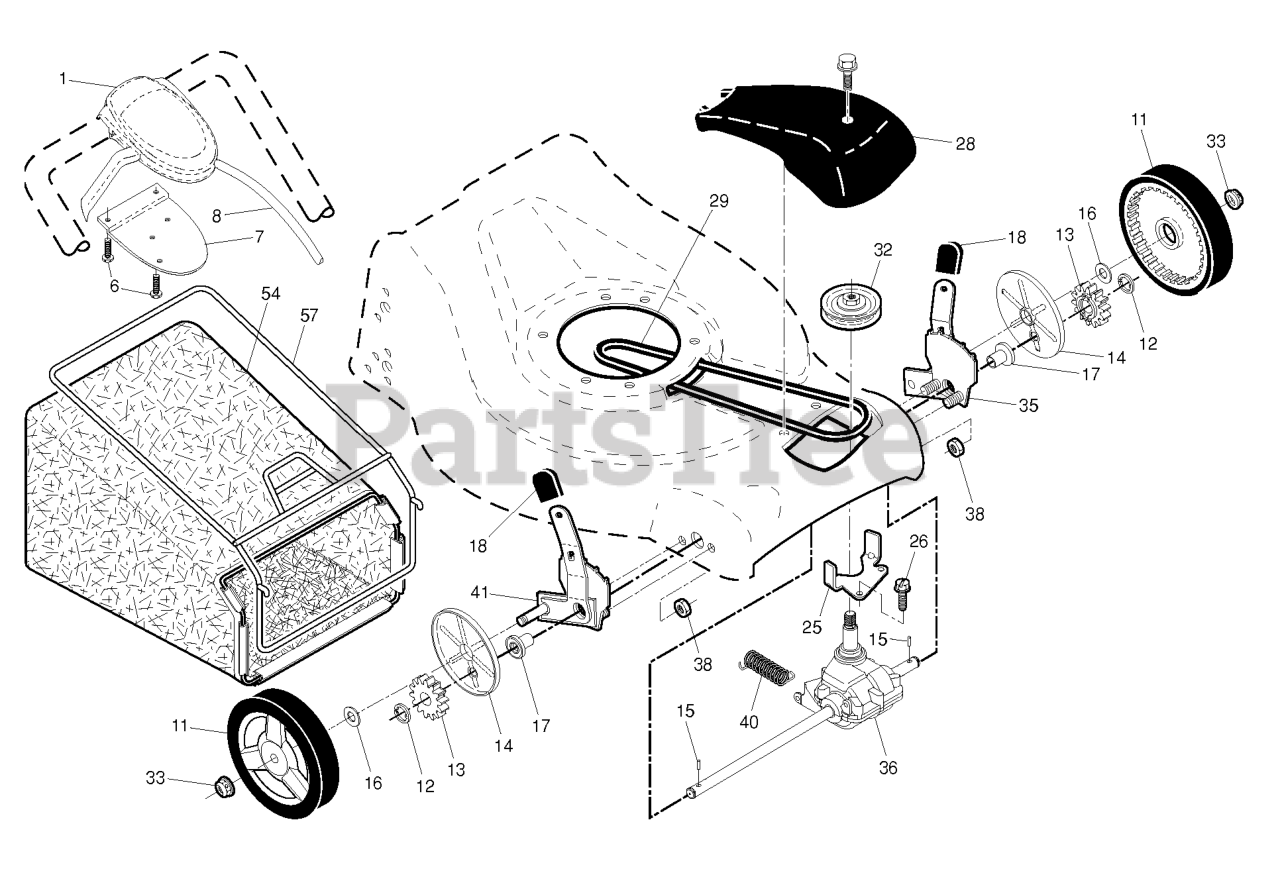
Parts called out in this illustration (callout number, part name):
1	CONTROL.DR.QW.21FGD.BS.GY/BLK
6	SCREW, PHILLIPS HEAD 10 X 5/8
7	BRACKET.DRIVE.CONTROL.MOUNT.BL
8	CABLE ASSEMBLY, DRIVE
11	WHEEL.8X1.75.H3SPK.RAD3.GY.BU3
12	E-RING 7/16 RE
13	PINION.14.TEETH.FGD
14	COVER.DUST.WHEEL
15	PAWL, DRIVE
16	WASHER FLUT
17	BEARING.ASM.
18	SELECTOR KNOB
25	BELT KEEPER
28	COVER.DRIVE.ASM.185579.CE.WALK
29	BELT.DRIVE.FG
32	RP PULLEY.DRIVE.EZ
33	NUT.HEX.FLANGE.3/8-16.LO(3 2)
35	KIT ADJUSTER ASM.438151.
36	TRANSMISSION.21.FGD.HT.VST
38	LOCKNUT.NYLOC.1/4-20
41	KIT ADJUSTER ASM.438148
54	Grassbag Assembly
57	FRAME.GBAG.21.FWGD
